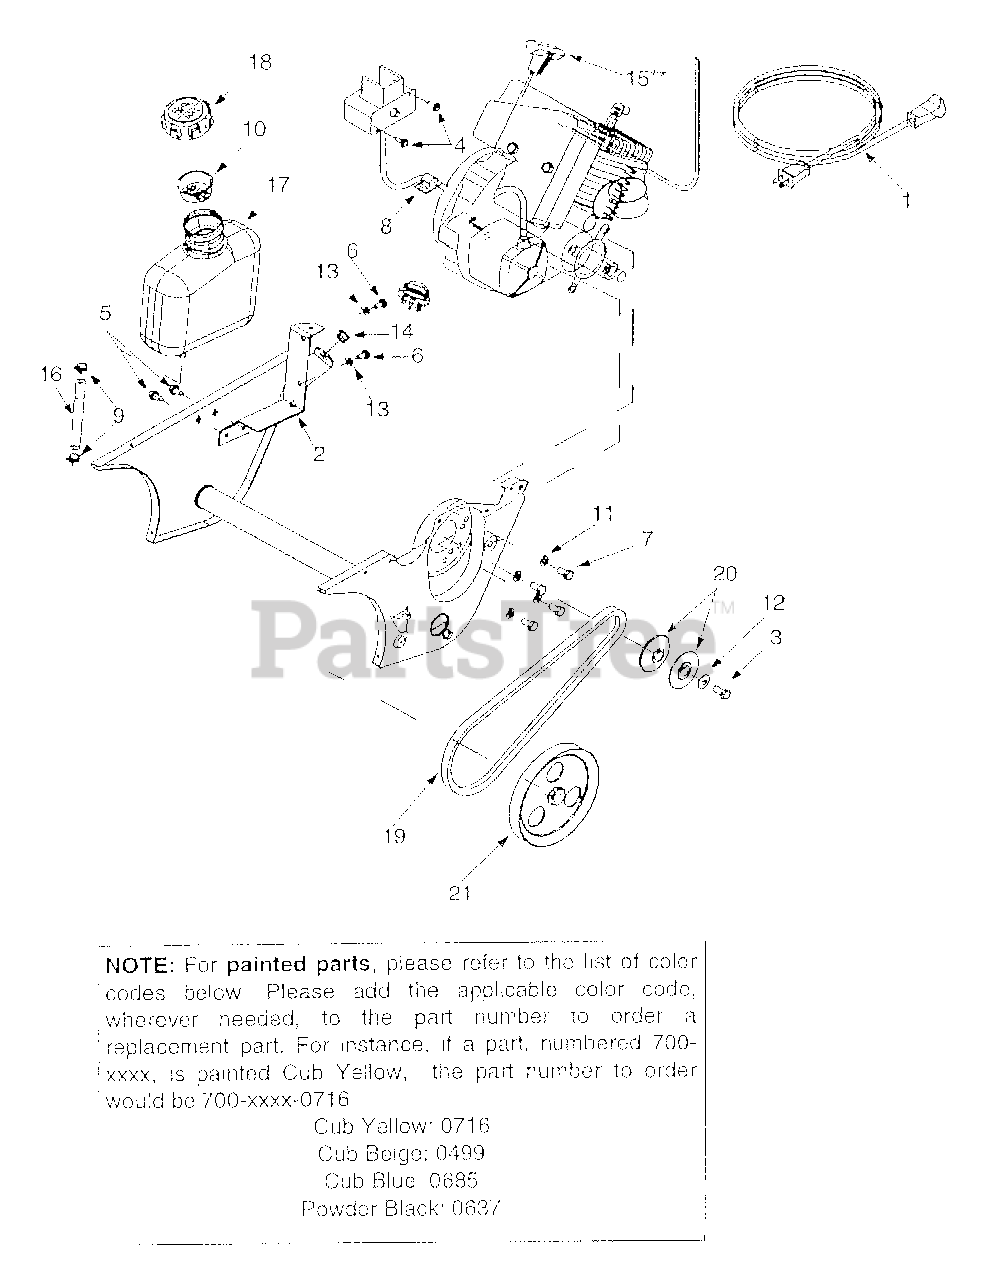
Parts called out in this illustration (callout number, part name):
1	Extension Cord
4	Special Screw
5	Self-Tapping Screw
6	Hex Screw 1/4-20 x .50"
7	Hex Screw 5/16-24 x .625
8	Mounting Clamp
9	Hose Clamp
11	Lock Washer
12	Beleville Washer
13	Lock Washer
14	Plastic Bushing
15	Recoil Handle
16	Fuel Line Hose
17	Fuel Tank: 2 Quart
18	Fuel Cap
19	V-Belt
20	V-Pulley Half
